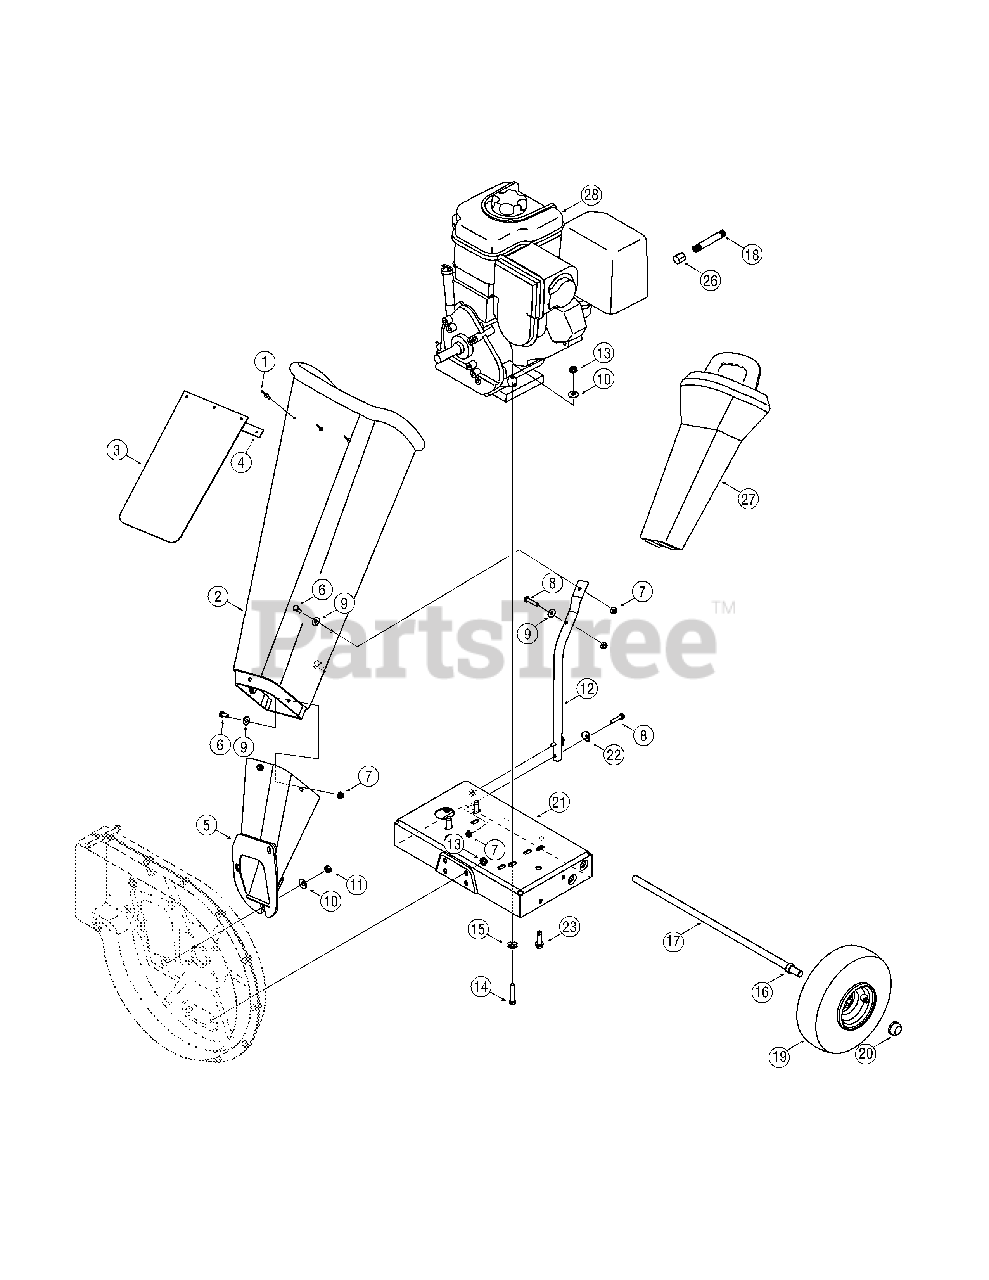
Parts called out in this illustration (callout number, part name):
1	Pop Rivet
2	Chipper Shredder Chute
3	Chute Flap
4	Chute Flap Strip
5	Chipper Chute Assembly
6	Hex Cap Screw 1/4 -20 x.620
7	Hex Lock Nut 1/4-20
8	Hex Cap Screw 1/4-20 x 1.25
9	Flat Washer .28 ID x .74 OD
10	Bell Washer .340 ID x .872 OD
11	Hex Nut 5/16-18
12	Support Brace
13	Hex Lock Nut 5/16-18
14	Hex Cap Screw 5/16-18 x 1.75
15	Bell Washer 5/16 x 1.0
16	Spacer
17	Axle Assembly
18	Pipe, Oil Drain
19	Wheel Complete, 10.0 x 4.0 Gray
20	Push Cap
22	Washer,.320 ID x.93 OD
23	Screw, 3/8-16 x 1.250
26	Oil Drain End Cap
27	Tamper
28	Engine
